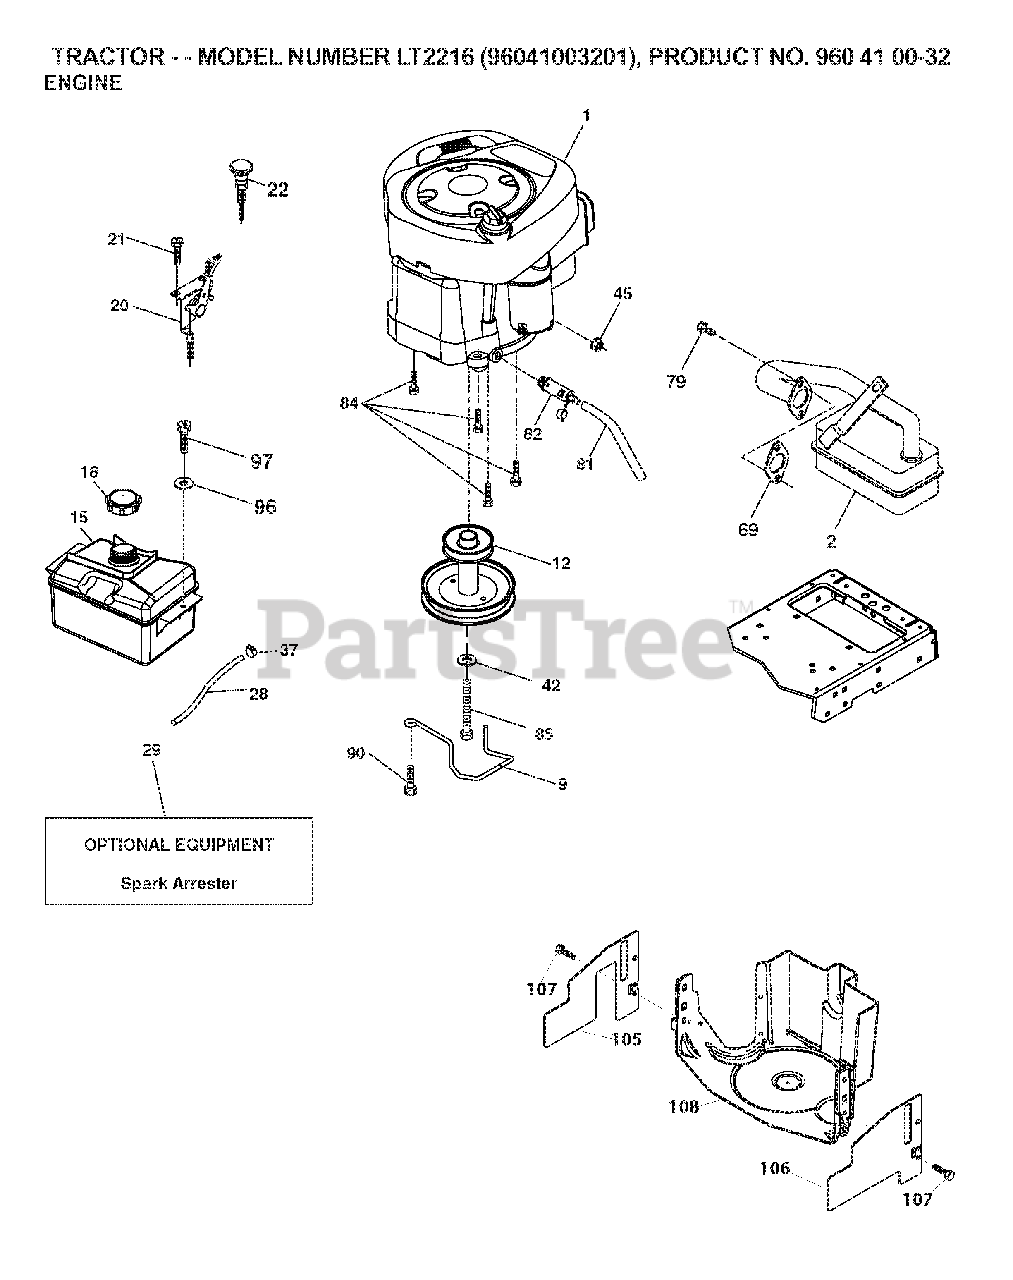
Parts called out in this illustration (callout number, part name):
9	KEEPER.BELT.ENGINE.3.25
12	PULLEY ENGINE
15	TANK FUEL FRT 1.5 GAL
18	FUEL CAP
20	CONTROL.TH/CK.C.
21	SCREW
28	LINE.FUEL.20
29	ARRESTER SPARK (OPTIONAL)
37	HOSE CLAMP
42	LOCKWASHER
45	NUT
69	REPL BY 532 27 22-93
79	SCREW.SOCKET HD.5/16-1
81	TUBE, DRAIN OIL ASM.
82	PLUG DRAIN OIL EASY
84	SCREW.3/8-16
85	BOLT HEX 7/16-20X4-1/4"
90	SCREW 3/8-16X1
97	SCREW HEXWSHR 1/4-20X3/4
107	SCREW.1/4-20X5/8
